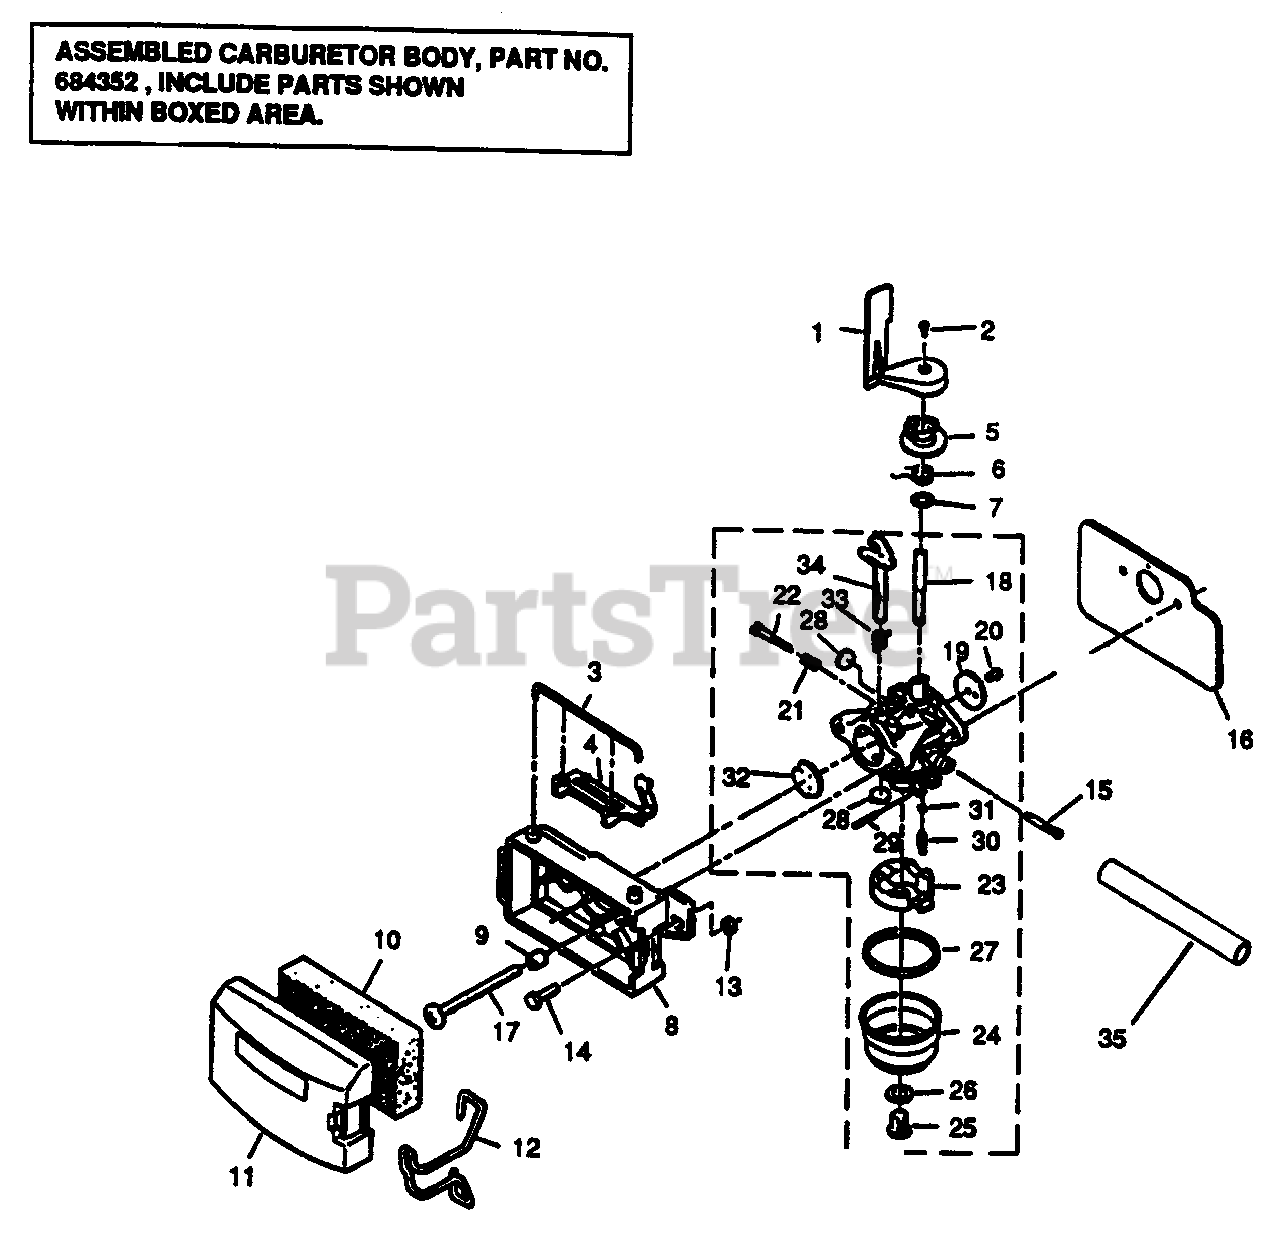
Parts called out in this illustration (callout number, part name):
1	Air Vane
2	Screw-Air Vane
3	Retainer-Speed Control Lever
4	Governor Control Lever
5	Collar
6	Spring
7	Washer
8	Air Filter Base
9	Spacer-Air Filter Base
10	Air Filter Element
11	Air Filter Cover
12	Air Filter Cover Retainer
13	Nut, Hex-Throttle Cable
14	Screw-Throttle Cable
15	Fuel Filter
16	Heat Shield & Gasket
17	Screw-Carburetor Mounting
18	Throttle Shaft
19	Throttle Valve
20	Screw-Throttle Valve
21	Spring-Idle Needle
22	Idle Needle
23	Float Assembly Kit
24	Fuel Bowl
25	Screw-Bowl-Retainer
26	Bowl Retainer Gasket
27	Fuels Bowl Gasket
28	Plug-Welch
29	Float Shaft
30	Inlet Needle Valve
31	Valve Seal
32	Choke Valve
33	Choke Return Spring
34	Choke Shaft
35	Fuel Line
